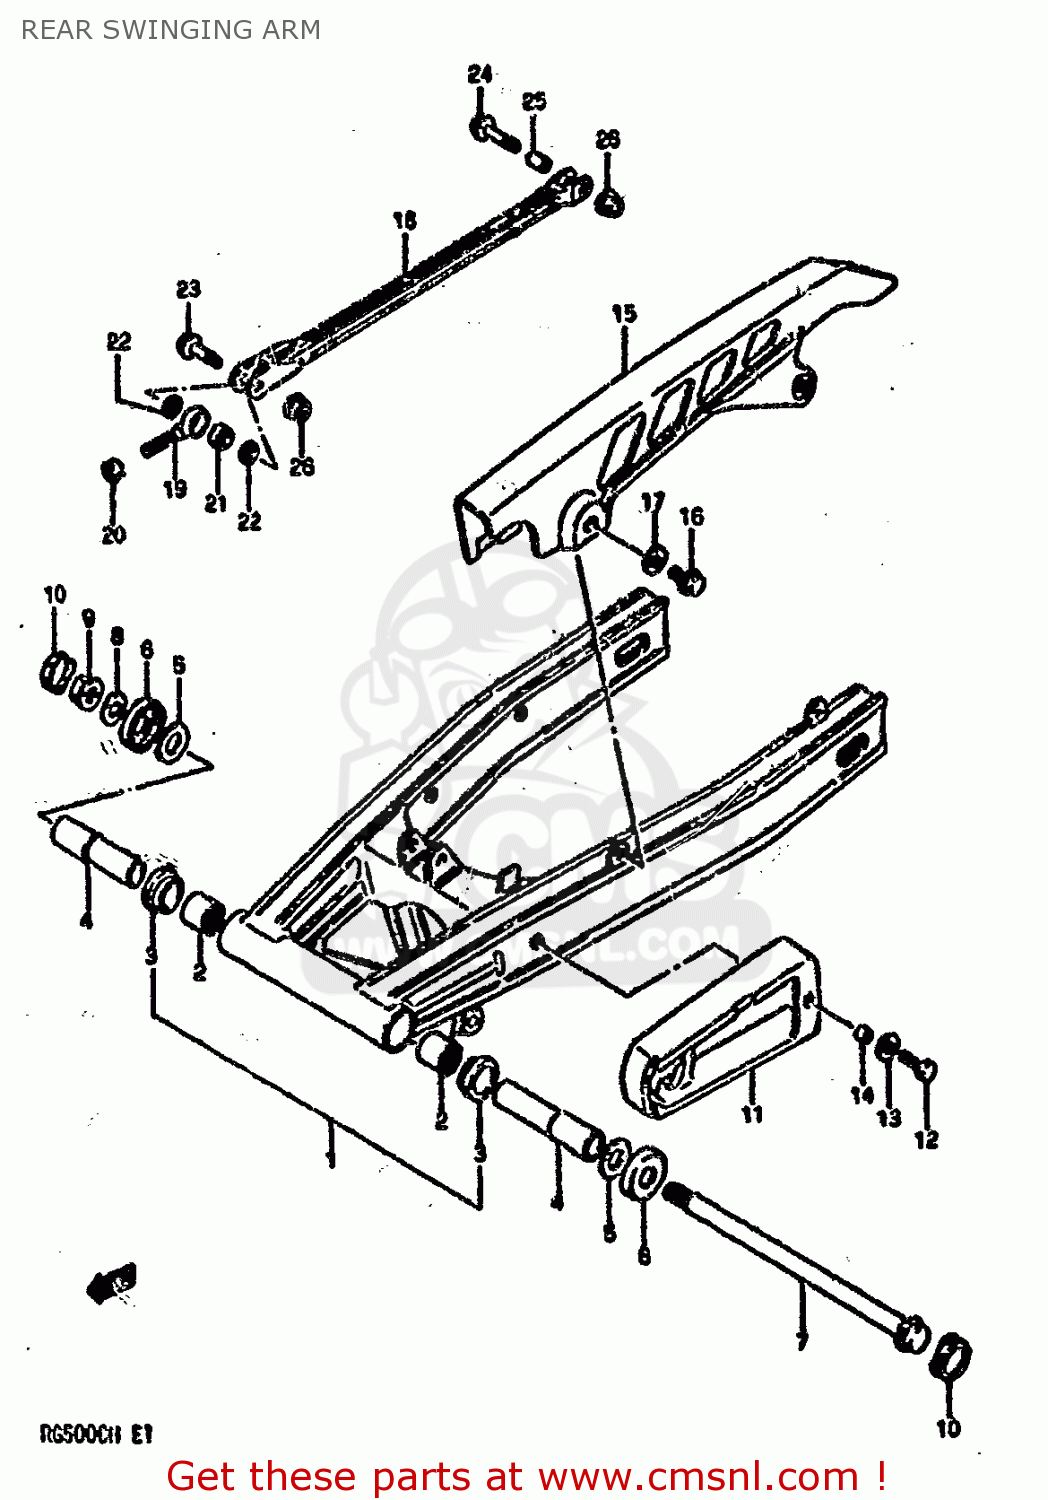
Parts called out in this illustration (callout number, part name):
1	SWINGING ARM ASSY,REAR
2	BEARING(22X29X30)
3	BUSHING,RR SWGARM PIVOT
4	SPACER,RR SWGARM PIVOT
5	WASHER(14.2X34X1)
6	COVER,RR SWINGING DUST SEAL
7	SHAFT
8	WASHER(14.2X26X1.2)
9	NUT
10	CAP,SWINGINGARM PIVOT
11	BUFFER
12	BOLT 5X20
13	WASHER
14	SPACER (5.5X8X4)
15	CASE, CHAIN
16	BOLT
17	WASHER
18	TORQUE LINK,REAR
19	HOUSING,TORQUE LINK BEARING
20	NUT
21	BEARING(8X18X11)
22	23
23	BOLT(8X31)
24	BOLT(8X35)
25	SPACER,RR TORQUE LINK RR
26	NUT
